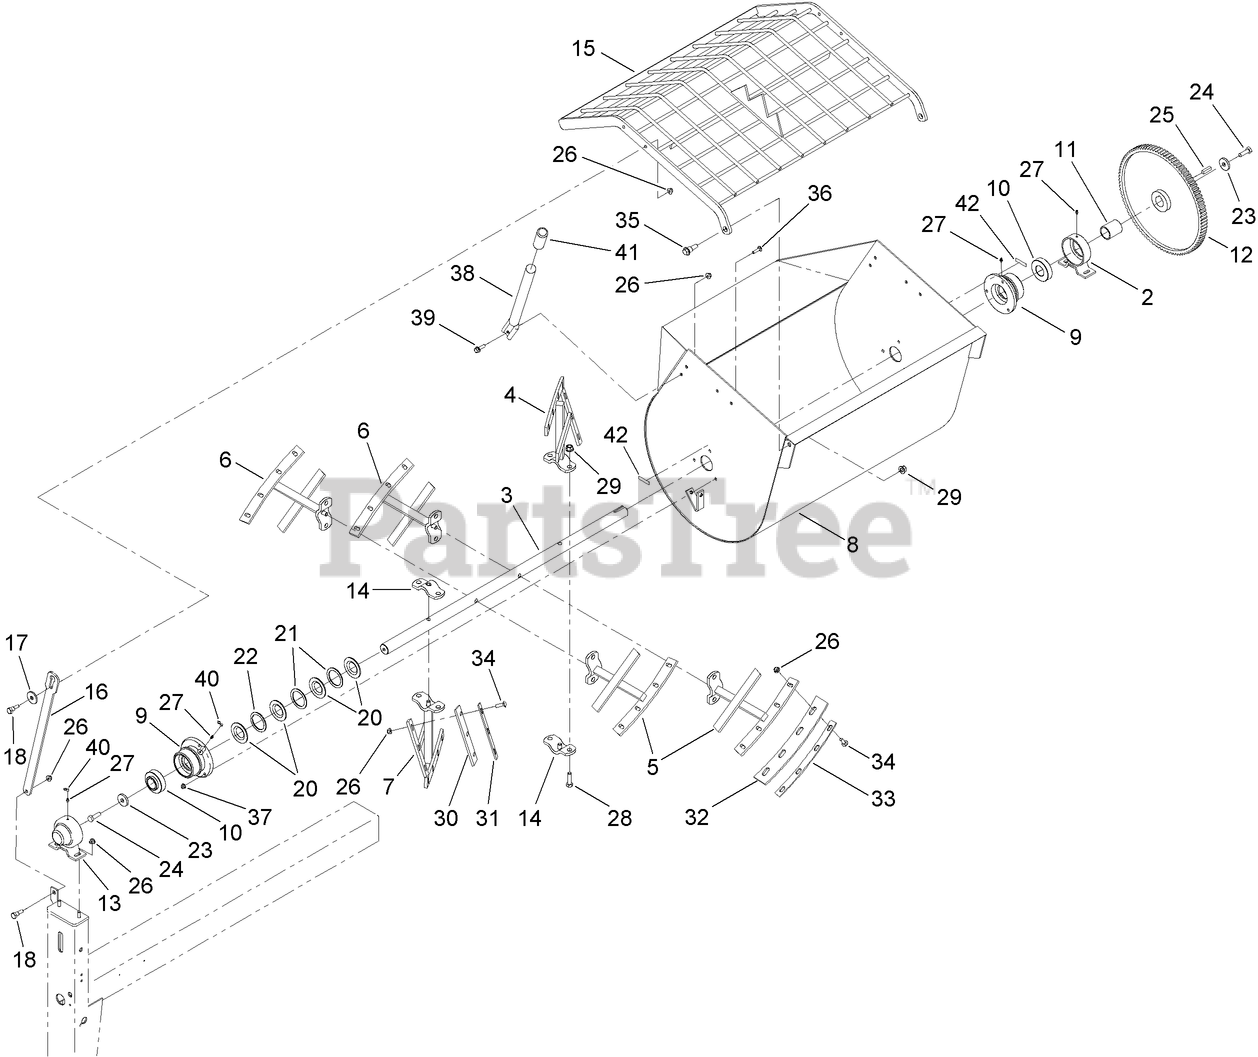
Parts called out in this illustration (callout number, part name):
2	TRUNNION
3	SHAFT-DRUM
9	HOUSING-BEARING
10	BEARING-BALL
11	SPACER-SHAFT, DRUM
12	GEAR-94 TEETH
13	TRUNNION-CAPPED
15	GUARD-DRUM
16	BAR-GUARD, LIFT
17	Washer-Thrust
18	BOLT-SHOULDER
20	SEAL-DRUM
21	WASHER-FLAT
22	WASHER-SPLIT
23	WASHER-FLAT
24	SCREW-HH
25	KEY-SQUARE
26	NUT-HF, NI
27	FITTING-GREASE
28	SCREW-HH
29	NUT-LOCK
30	BLADE-RUBBER, SHORT
31	BAR-BACKER, SHORT
32	BLADE-RUBBER, LONG
33	BAR-BACKER, LONG
34	BOLT-CARR
35	SCREW-SHOULDER, HHF
36	SCREW-CARR
37	NUT-HF, NI
38	HANDLE-DUMP
39	SCREW-HHF
40	CAP-PLUG
41	GRIP-HAND
42	DECAL-GREASE
